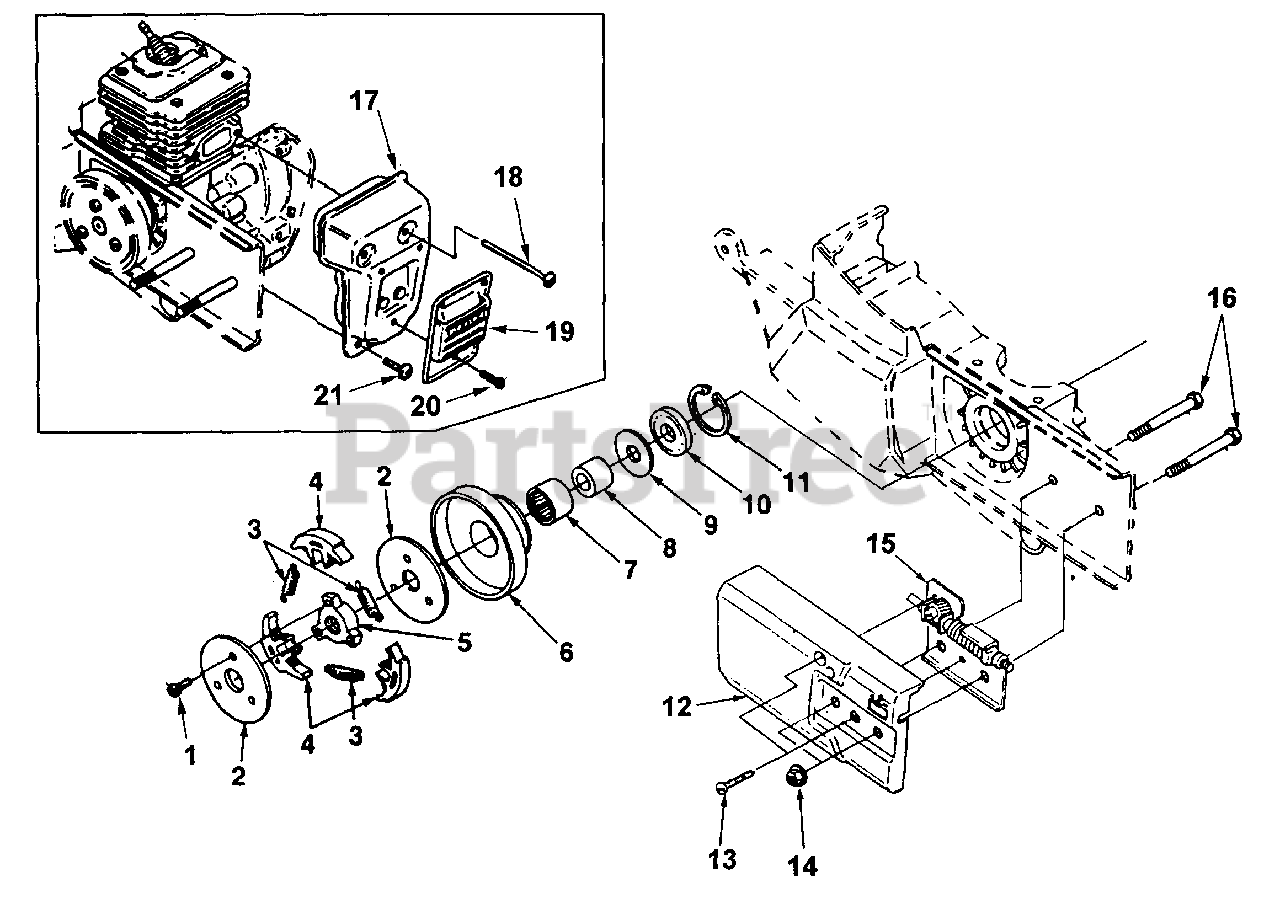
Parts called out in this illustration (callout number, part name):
1	SCREW-Machine Hex Hd. (8-32 X 3/8")
2	COVER-Clutch
3	SPRING-Clutch
4	SHOE-Clutch
5	CLUTCH-Spider
6	PULLEY-Drum & Bearing
7	BEARING-Needle
8	RACE-Inner
9	WASHER-Thrust
10	SEAL-Main
11	RETAINER-Bearing
12	CLUTCH-Cover
13	SCREW- Taptite (8-32 x 5/8")
14	NUT-Hex Flange (5/16-18)
15	GEAR KIT
16	BOLT-Wheel Arm
17	MUFFLER
18	SCREW-Truss Hd. (10-24 x 2 1/2")
19	CAP- Muffler
20	SCREW-Machine Hex Hd. (8-32 x 1/2")
21	SCREW-Torx (10-24 x 1/2")
